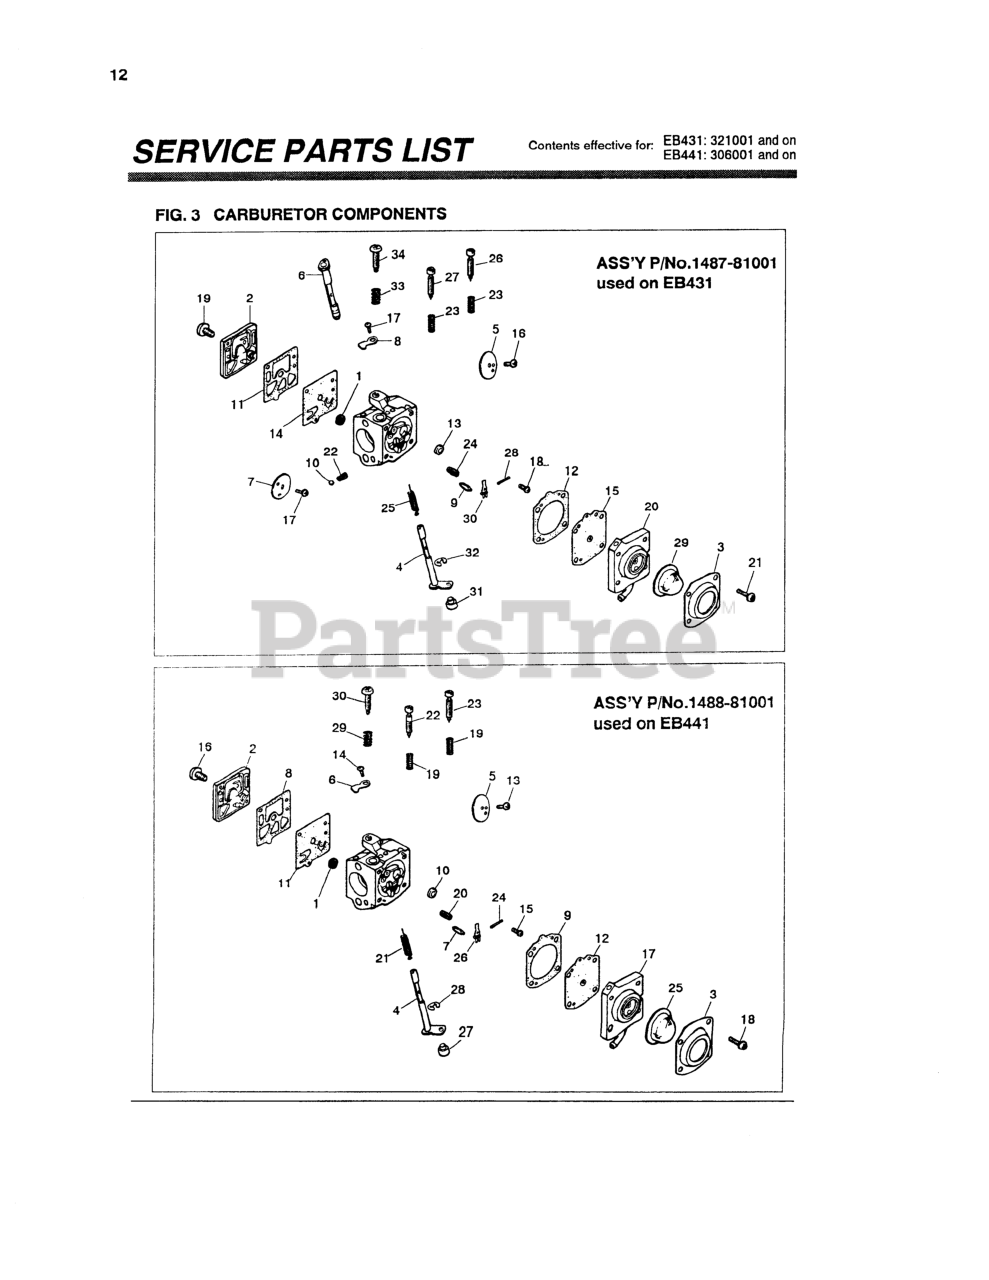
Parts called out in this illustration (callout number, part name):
2	COVER, PUMP
3	COVER, PUMP
4	SHAFT ASSEMBLY
5	VALVE, THROTTLE
6	THROTTLE STOP
7	VALVE, INLET
8	KIT ONLY
9	KIT ONLY
10	PLUG, WELSH
11	KIT ONLY
16	SCREW (RPLS 1491-81130)
17	BODY ASSY (RPLS 1491-81490)
18	SCREW (REPLACES 1491-81350)
20	KIT ONLY
21	SPRING
22	NEEDLE (H)
24	PIN, METERING LEVER
25	PUMP, PRIMER
26	KIT ONLY
27	SWIVEL (USE -06040)
29	SPRING, IDLE
NI	REBUILD KIT, EB430/440
NI	EB430/40 DIA/GASK KIT
